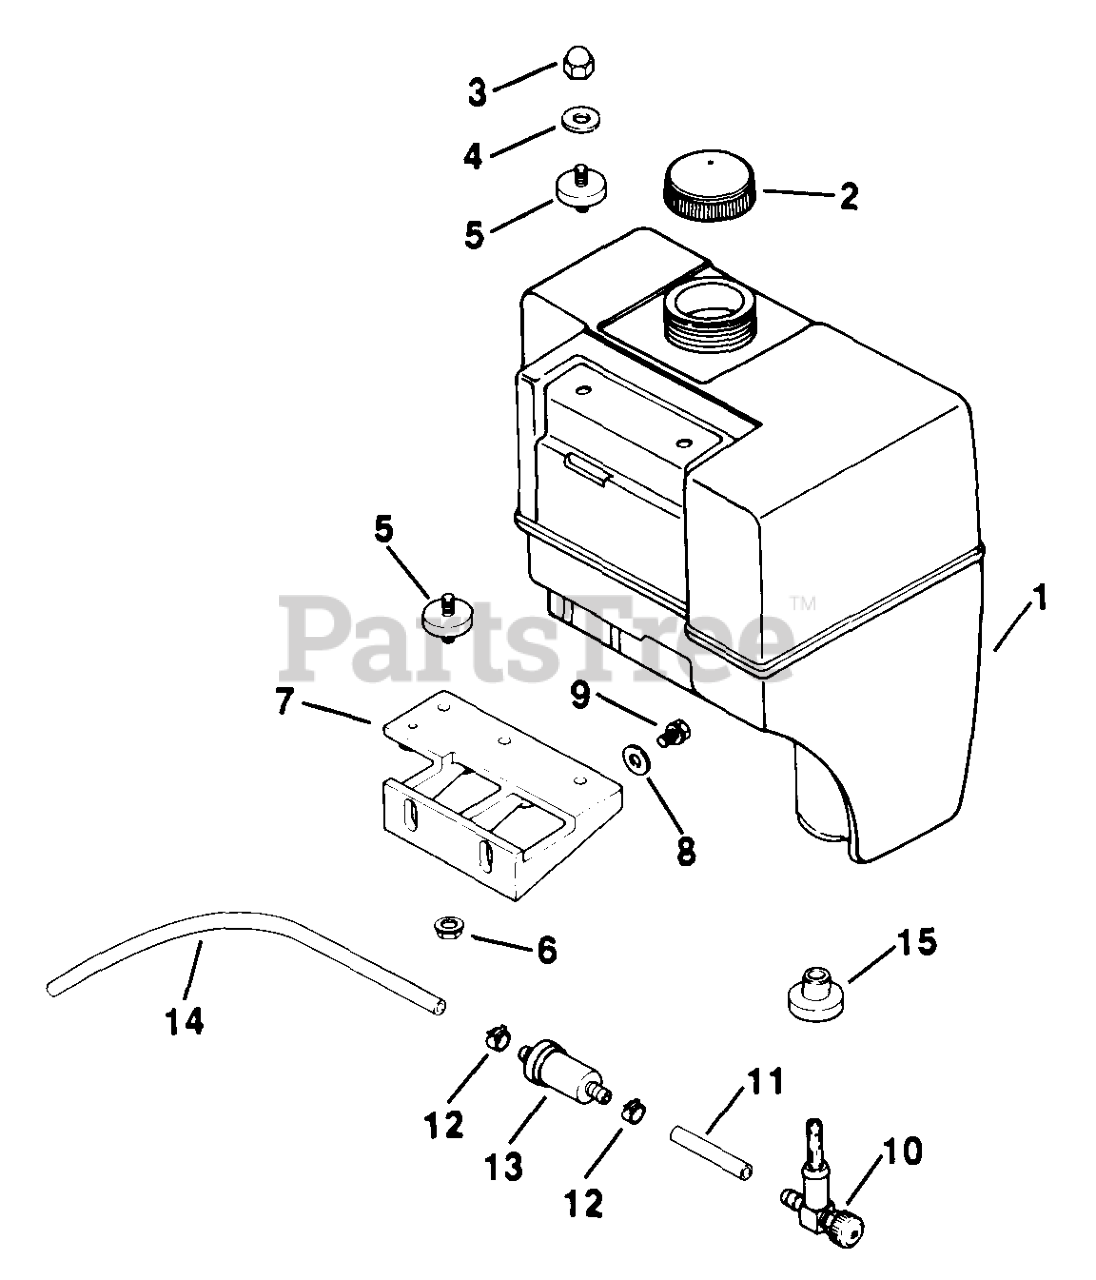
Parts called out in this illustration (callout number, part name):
1	KIT - USE 47 755 39
1	KIT, FUEL TANK
2	CAP - USE 25 173 02
3	NUT - (#DSC)
4	WASHER, PLAIN 1/4"
5	KIT - USE 47 760 01
6	PALNUT, 1/4-20
9	SCREW, SEMS 3/8-16X1-1/4" - DISCONTINUED
10	VALVE
11	LINE - DISCONTINUED
13	FILTER - USE 41 050 03
15	BUSHING, FUEL TANK
